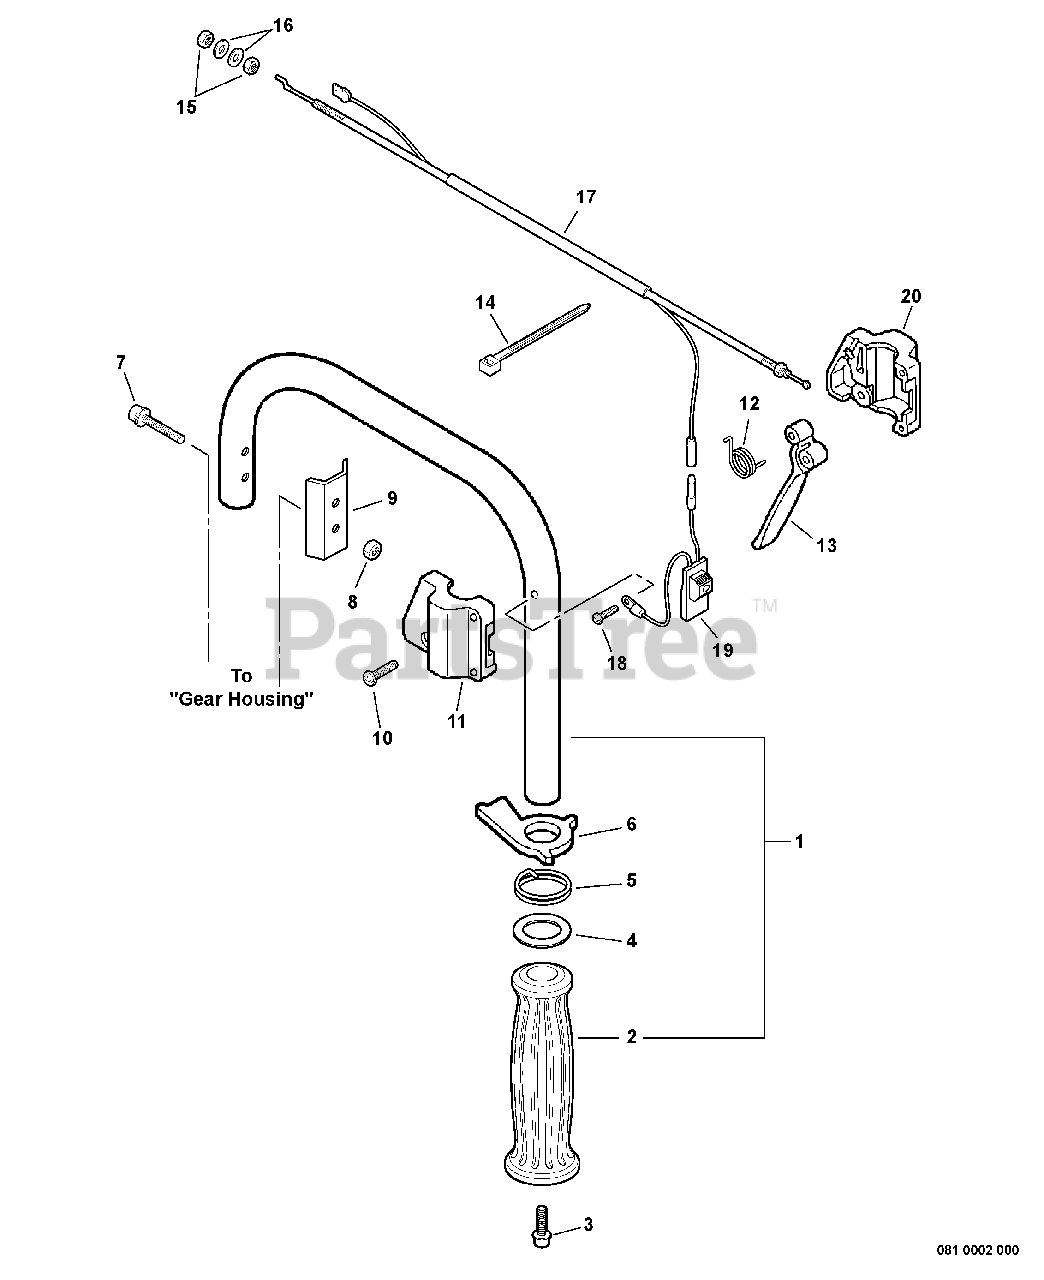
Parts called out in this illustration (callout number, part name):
1	HANDLE ASSY - REAR
2	GRIP, HANDLE - RIGHT
3	SCREW - 5X16
5	SPRING, LOCKOUT LEVER
6	LEVER, TRIGGER LOCKOUT
7	SCREW - 5X35
8	LOCKNUT - 5
9	PLATE, HANDLE
10	SCREW - 4X25
11	BRACKET, THROTTLE CONTROL - LEFT
12	SPRING, TRIGGER
13	TRIGGER, THROTTLE
14	TIE, CABLE
16	WASHER - 6
17	CONTROL CABLE ASSY
18	SCREW - 4X30
19	IGNITION SWITCH ASSY
20	BRACKET, THROTTLE CONTROL - RIGHT
